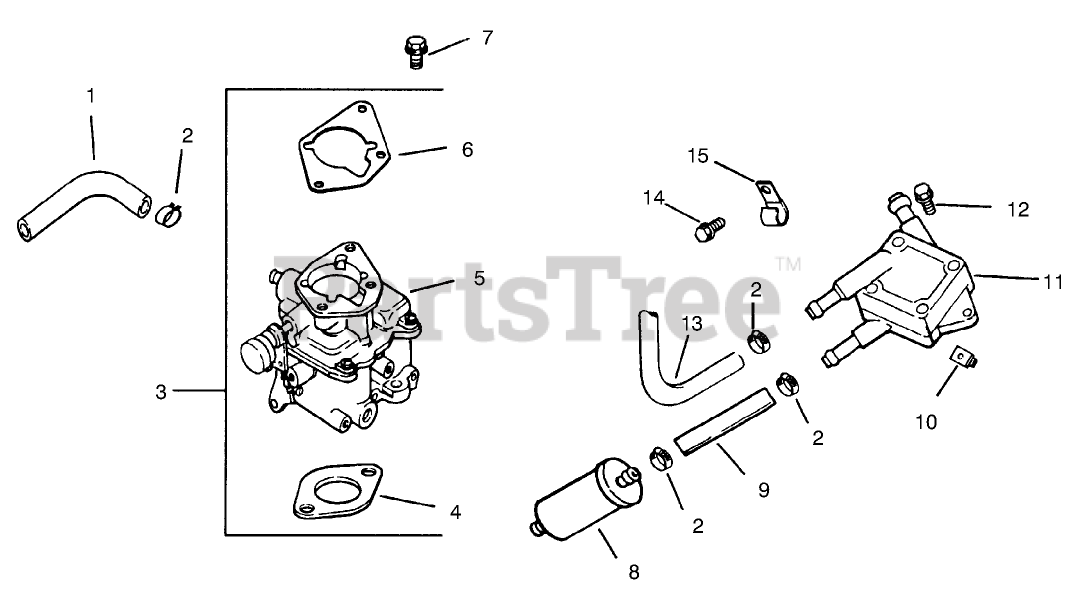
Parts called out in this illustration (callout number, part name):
1	Line fuel
2	Clamp
3	Kit, carburetor w/gasket (Includes 4-6)
4	Gasket
5	Carburetor ASM
6	Gasket
7	Screw
8	Filter-Fuel
9	Line-Fuel
10	Nut
11	Pump-Fuel
12	Screw
13	Line, fuel
14	Screw
15	Clamp
